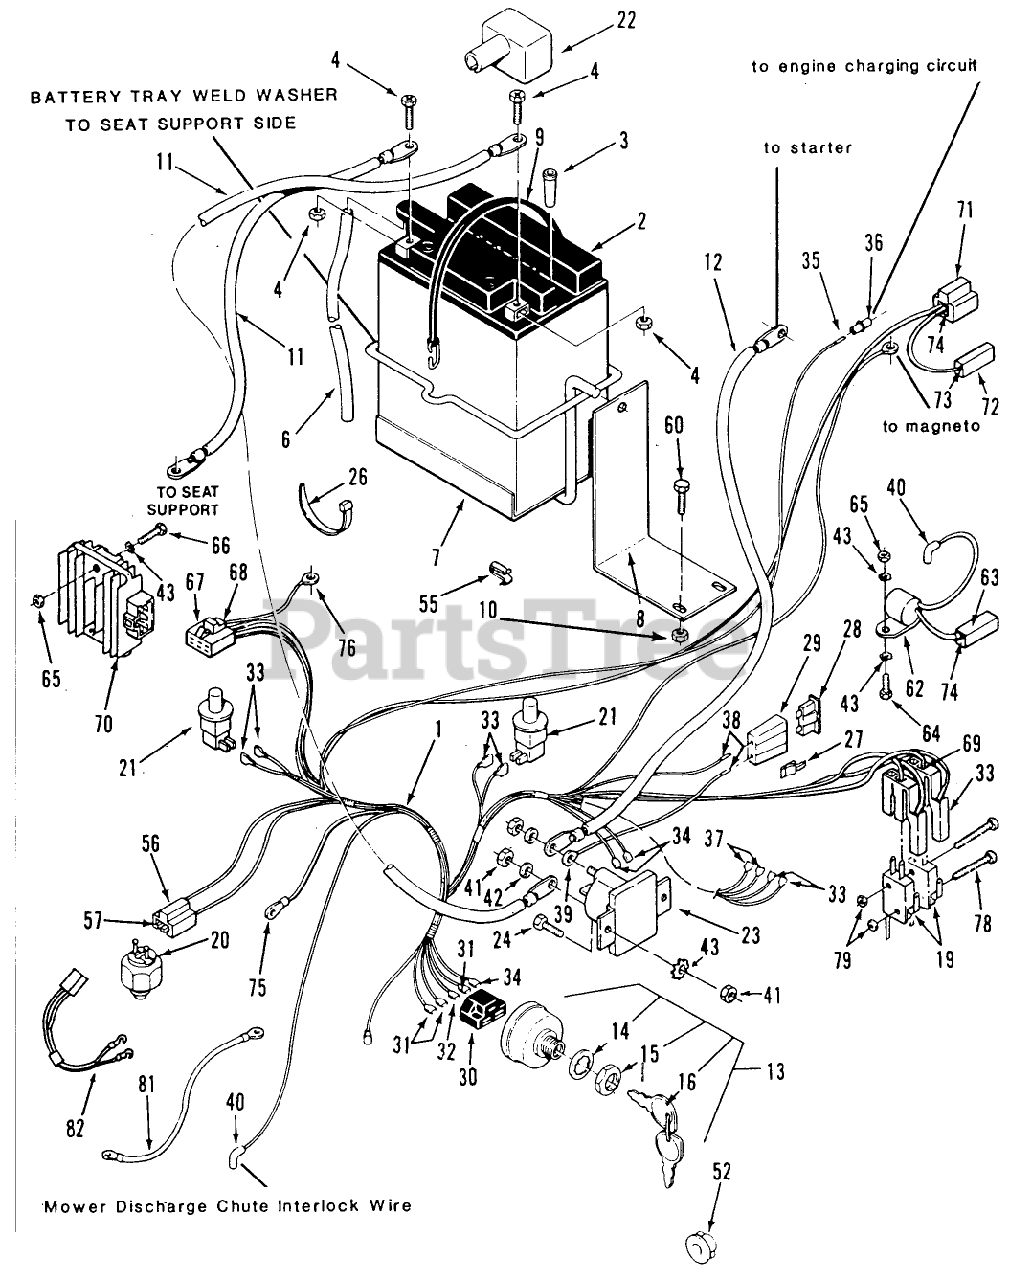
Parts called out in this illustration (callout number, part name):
1	WIRING-HARNESS & DIA
7	BATTERY TRAY *B
8	BRACKET *B
12	WIRE ASM
19	SWITCH-LEVER
20	SWITCH (N.C.-TRANS)
28	FUSE-BLADE, 15 AMP
33	OBTAIN LOCALLY
34	Connector .250 x .032
37	Wire Terminal (Part of 1)
52	BUSHING-NYLON 1.093
55	CLIP
56	CONNECTOR BODY
63	CONNECTOR BODY ELECT
68	Terminal 212 (part of item 2)
69	CONNECTOR BODY
74	TERMINAL-LONG MALE
75	OBTAIN LOCALLY
76	Ring Terminal 1/4 (Part of 1)
81	WIRE-BONDING
82	ASSY WIRING HARNESS
